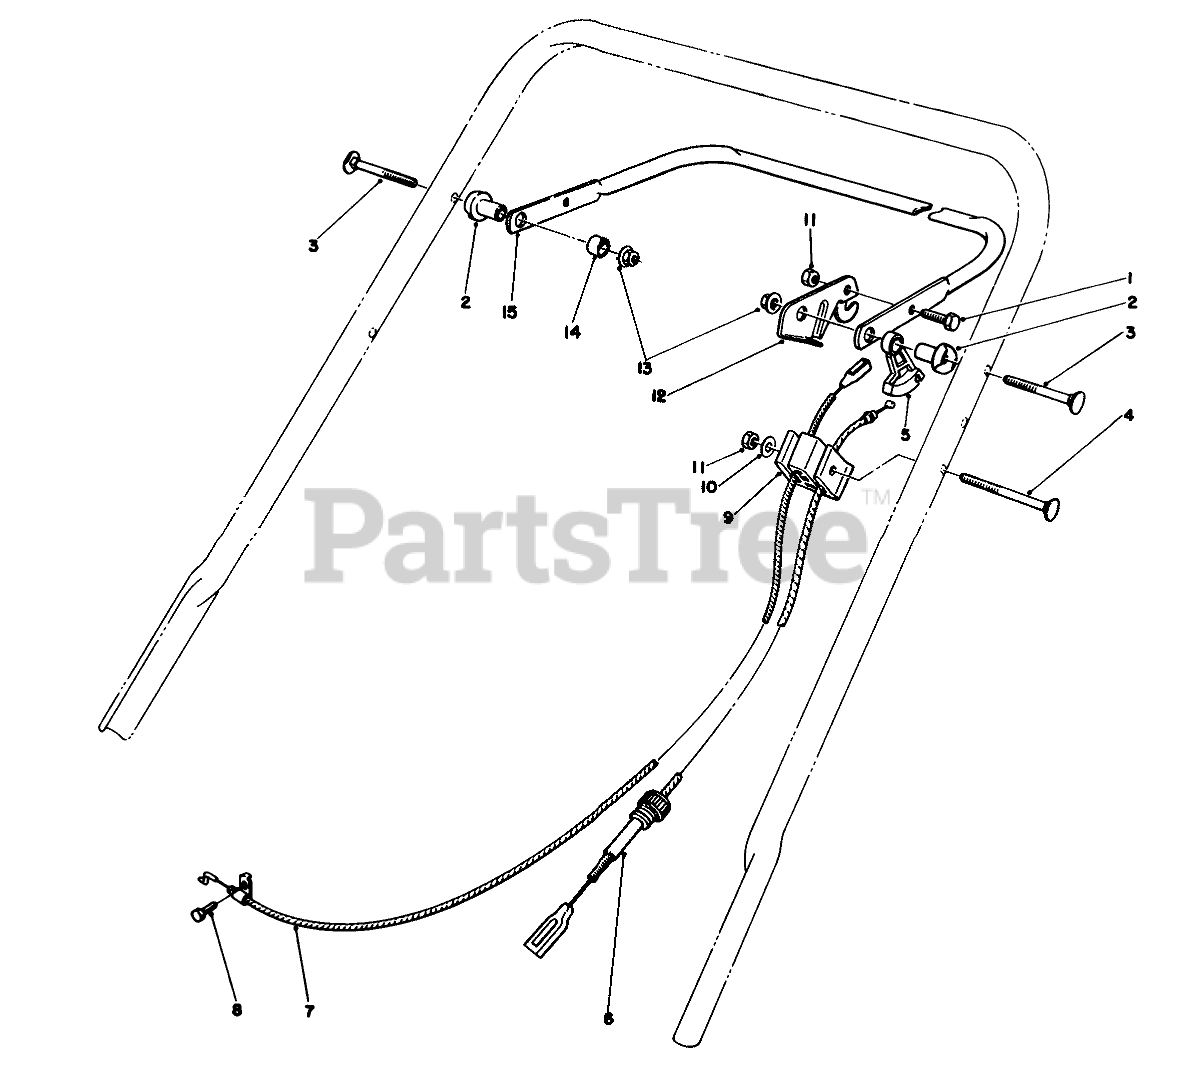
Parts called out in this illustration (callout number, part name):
1	SCREW-HH
2	SPACER-SUPPORT
3	5/16-18 X 2 HNDLE SCREW
4	HANDLE SCREW
5	LEVER-TRACTION
6	CABLE-TRACTION
7	BRAKE CABLE
8	SCREW-HH
9	SUPPORT-CABLE
10	WASHER-FLAT
11	NUT-LOCK, NI
12	LEVER-CONTROL
13	NUT-LOCK, NI
14	SPACER-NYLON
15	Bar-Control
